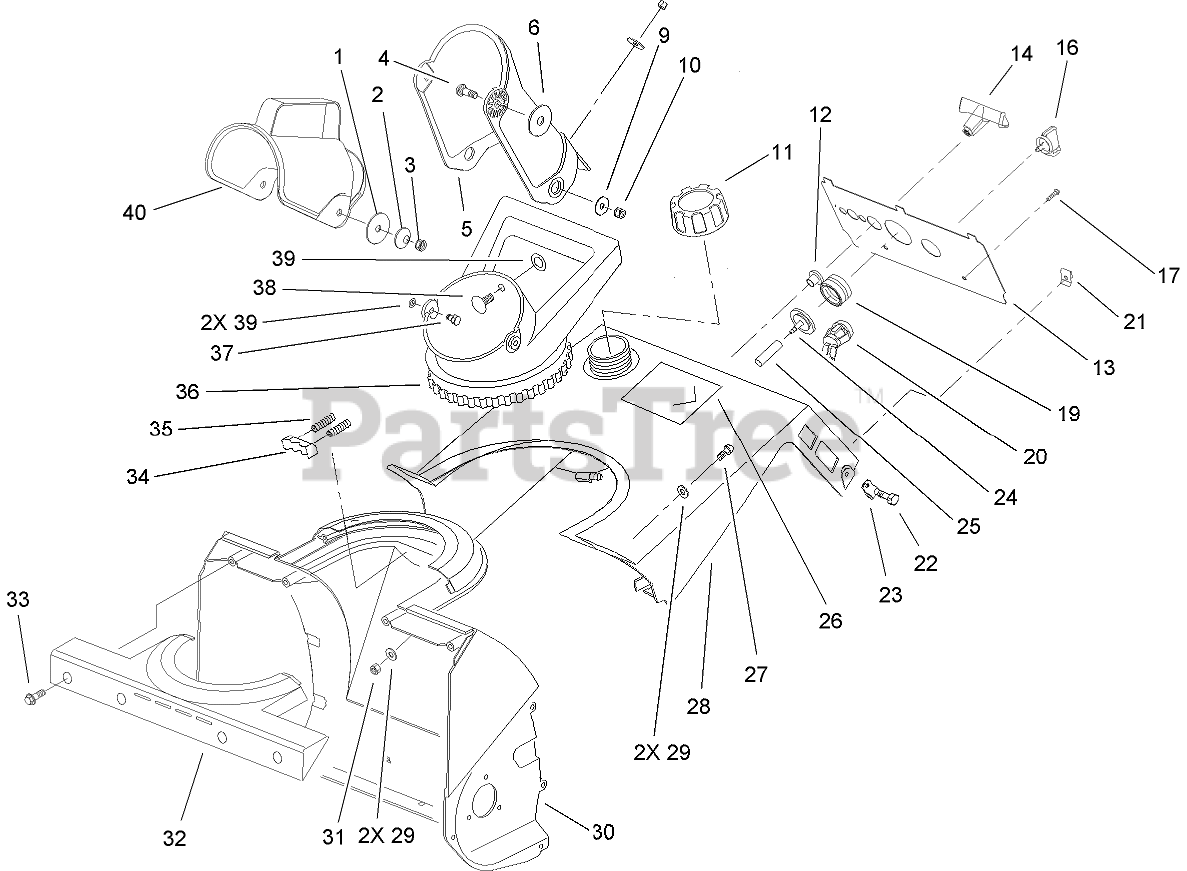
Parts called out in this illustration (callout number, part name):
1	WASHER-FLAT
2	WASHER-BELLEVILLE
3	NUT-LOCK, NI
4	BOLT-CARR
6	WASHER-RUBBER
9	WASHER-FLAT
10	NUT-LOCK, NI
11	GAS CAP ASM
12	GUIDE-ROPE, STARTER
13	PANEL-CONTROL
14	HANDLE-STARTER
16	KEY-IGNITION
17	SCREW-SHWH, THREAD FORMING
19	BULB-PRIMER
20	SWITCH
22	SCREW-THREAD FORMING
23	CLAMP
24	BODY-PRIMER
25	HOSE-PRIMER
26	DECAL-SHROUD
27	SCREW-PPH
28	SHROUD-TANK, GAS UPPER
29	WASHER-FLAT
30	HOUSING
31	NUT-LOCK, NI
32	RETAINER-CHUTE
33	SCREW-PLASTIC
34	DETENT-CHUTE
35	SPRING-COMPRESSION
36	HANDLE-CHUTE
37	SCREW-HH
38	SCREW-CARR
39	PUSHNUT-RETAINER, BOLT
40	DEFLECTOR-CHUTE
